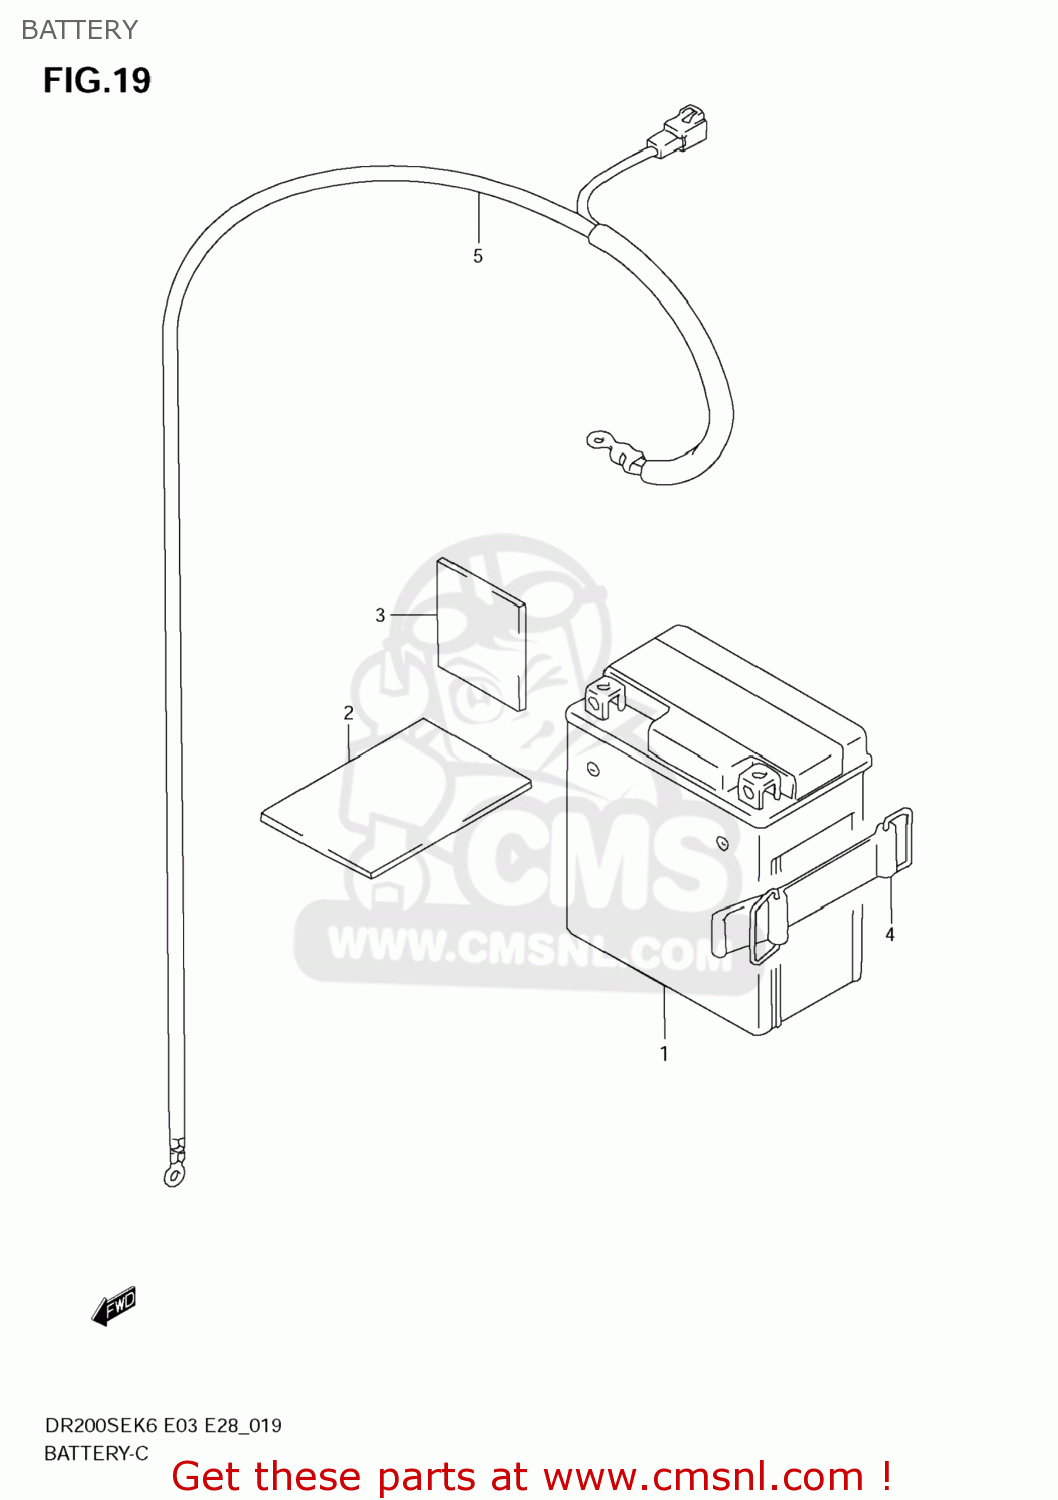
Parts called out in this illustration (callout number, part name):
1	BATTERY ASSY(YTX7L-BS,12V6AH)
2	PROTECTOR(170X95X3.0)
3	PROTECTOR(170X95X3.0)
4	BAND
5	WIRE,BATTERY MINUS
